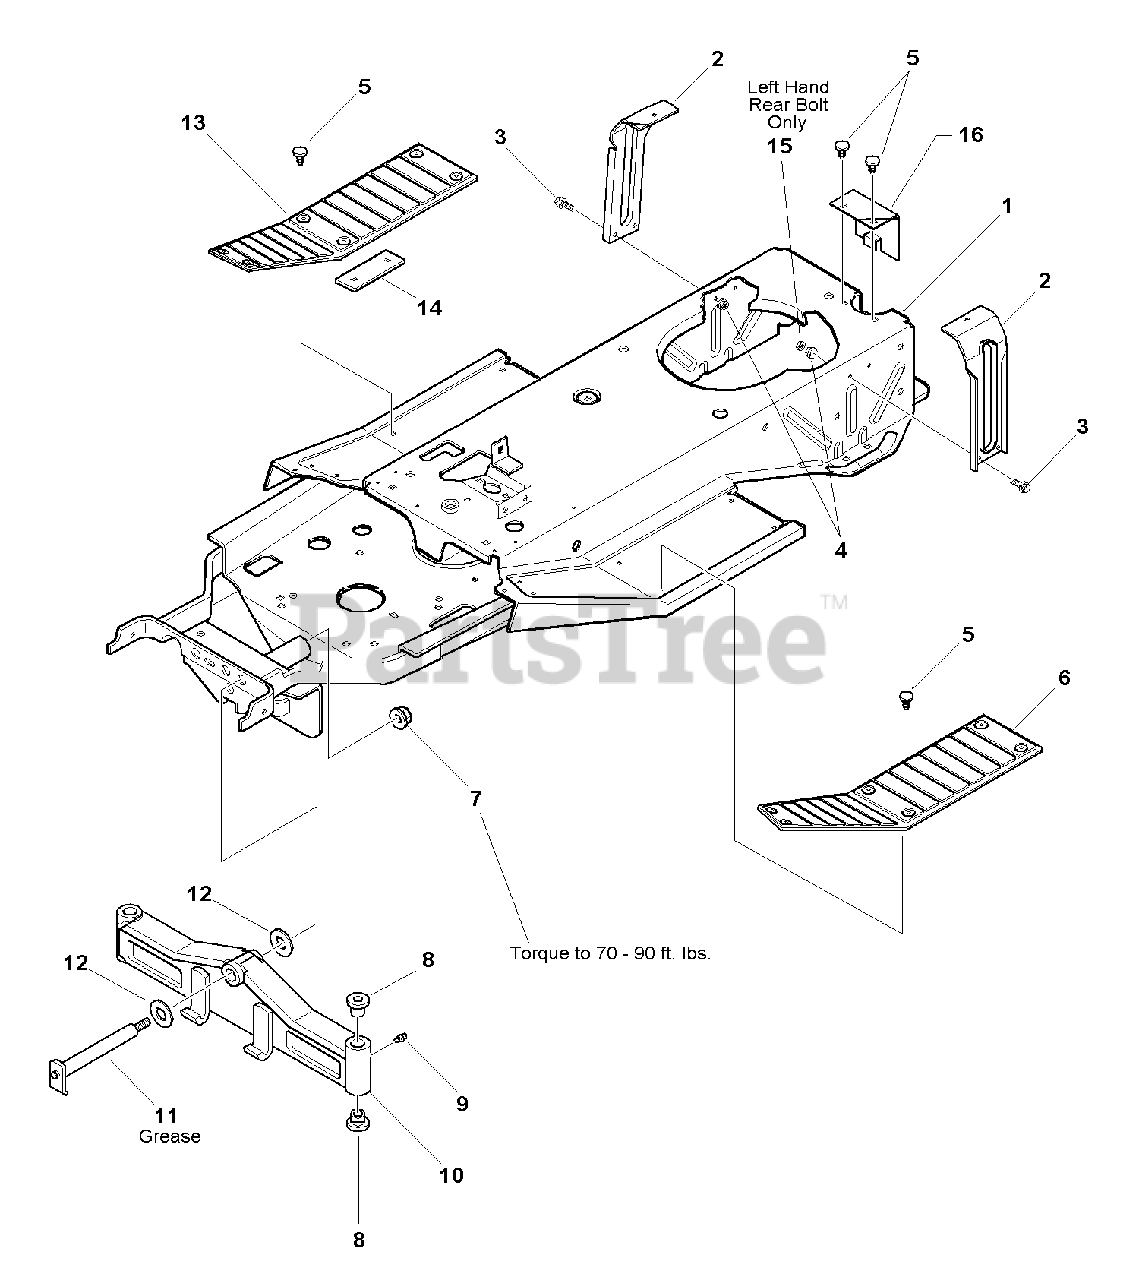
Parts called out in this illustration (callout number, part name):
1	FRAME ASSEMBLY
2	SUPPORT, Seat
3	CAPSCREW, Hex Flange Head, Whizlock, 3/8-16 x 1
4	NUT, Hex Nylon Lock, 3/8-16
5	FASTENER, Panel
6	PAD, Footrest, LH
7	NUT, Hex, Full Lock, 3/4-16
9	GREASE FITTING
10	AXLE ASSEMBLY, Front
11	AXLE PIVOT ASSEMBLY
12	WASHER, Special
13	PAD, Footrest, RH
14	PLATE, Cover
15	NUT, Jam, Hex, Center Lock, 3/8-16
16	COVER, Rear
